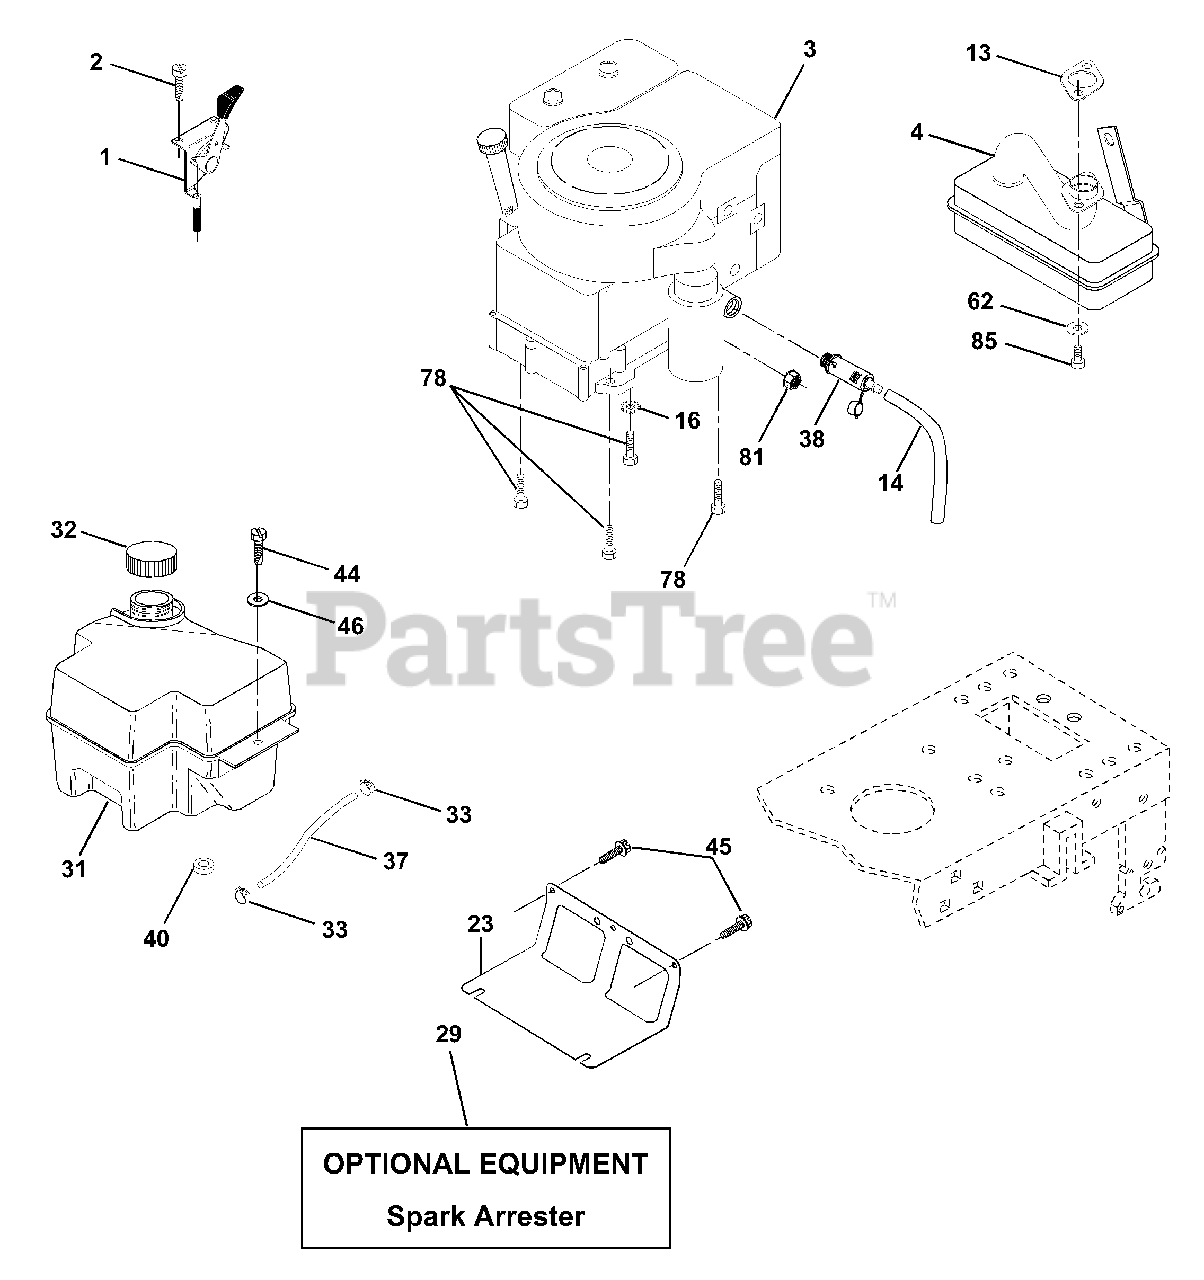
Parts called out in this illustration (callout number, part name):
1	Control Throt/Ch
2	Screw Hex Thd Cut 1/4-20 x 5/8 T
4	Muffler Tec 13.5/17 Lt
13	Gasket
14	Tube Drain Oil Easy
16	Washer Lock Ext Tooth 3/8
23	Shield Browning
29	Arrestor Spark
31	Tank Fuel 2.00 Fr
32	Cap Asm Fuel
33	Clamp Hose Blk
37	Line Fuel 20"
38	Plug Drain Oil Easy
40	Bushing Snap Nyl Blk Fuel Line
44	Screw Hexwsh Thdrol 1/4-20x3/4
45	Screw 5/16-18 x 3/4
46	Washer 9/32 X 7/8 X 16ga
62	Washer Lock Hvy Hlcl Spr 5/16
78	Screw 3/8-16x1-1/4
81	Nut Flange 1/4-20 Starter Nut
85	Bolt Hex Hd Phillips
